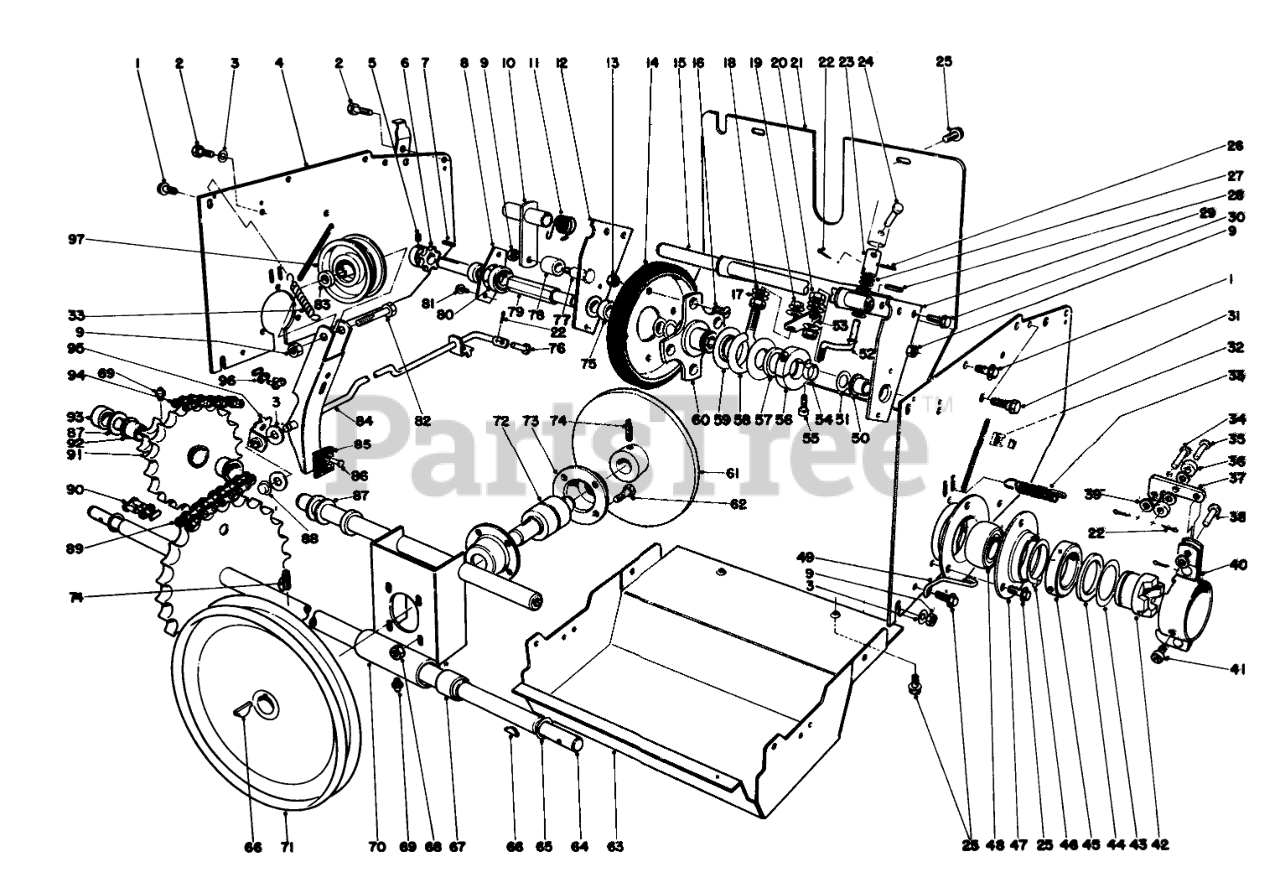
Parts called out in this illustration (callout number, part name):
1	SCREW-HHF
2	SCREW-HHFTF
3	WASHER-FLAT
4	Side Plate Drive
5	SCREW-HSH
6	SPROCKET
8	BEARING CUP
9	NUT-HEX
10	CHAIN TENSION ARM WA
11	TORSION SPRING
12	HEX SHAFT MOUNT R
13	Nut
14	Disc
15	Bracket Dead Shaft
16	5/16-18X5/8 FLT HD MS
17	WASHER-FLAT
18	WASHER-SPRING
19	NUT-LOCK, FLANGE
20	Nut
21	REAR COVER R
22	PIN-COTTER
23	U JOINT TUBE
24	CLEVIS PIN
25	SCREW-HWH
26	PIN-SPRING
27	Clevis Pin
28	PIN-ROLL
29	Hex Shaft Mounting (Incl. Ref. #503)
30	SCREW-HWHTF
31	SHOULDER SCREW
32	Retained Nut
33	EXTENSION SPRING
34	PIN-CLEVIS
35	PIN-CLEVIS
36	CLUTCH ROLLER
37	CLUTCH CAM ARM
38	PIN-CLEVIS
39	WASHER-FLAT
40	CLUTCH MT BRKT ASM
41	SCREW-HSH
42	WHEEL CLUTCH
43	THRUST WASHER
44	THRUST BEARING
45	CLUTCH MOUNT COLLAR
46	RING-RETAINING, EXTERNAL
47	BEARING FLANGE
48	BEARING
49	Clutch Retainer
50	BUSHING
51	WASHER-FLAT
52	CONNECTION ROD
53	SHIFT ROD PIVOT
54	SPLIT SPACER
55	SCREW-HSH
56	ColIar
57	WASHER-THRUST
58	SLIDER RING COLLAR
59	SLIDER RING
60	TRACTION DISC HUB
61	FRICTION PLATE O
62	SCREW-HH
63	LOWER SHIELD R
64	AXLE SHAFT WA
65	WASHER
66	KEY-WOODRUFF
67	BUSHING
68	NUT-KEPS
69	FITTING-GREASE
70	Bulkhead (Incl. Ref. #67)
71	Pulley
72	BEARING-FRICTION PLATE
73	HOUSING BEARING
74	SCREW-SET, SQH
75	SPACER
76	PIN-CLEVIS
77	SHOULDER BOLT
78	CHAIN TENSION ROLLER
79	FRICTION WHEEL SHAFT
80	BEARING
81	SCREW
82	SCREW-HH
83	Spacer
84	Auger Brake Assembly (Incl. Ref. #85-86)
85	BRAKE PAD
86	.185 DIA X .375 RT +
87	WASHER-THRUST
88	PUSH NUT
89	ROLLER CHAIN
90	LINK-CHAIN
91	Sprocket (Incl. Ref. #69 & 92)
92	3/4ID X 3/4LG BSHG
93	SPACER-IDLER
94	1/4 X 42 CHAIN W/LINK
95	Bracket-Clutch
96	LINK-CONNECTING
97	PULLEY-IDLER
